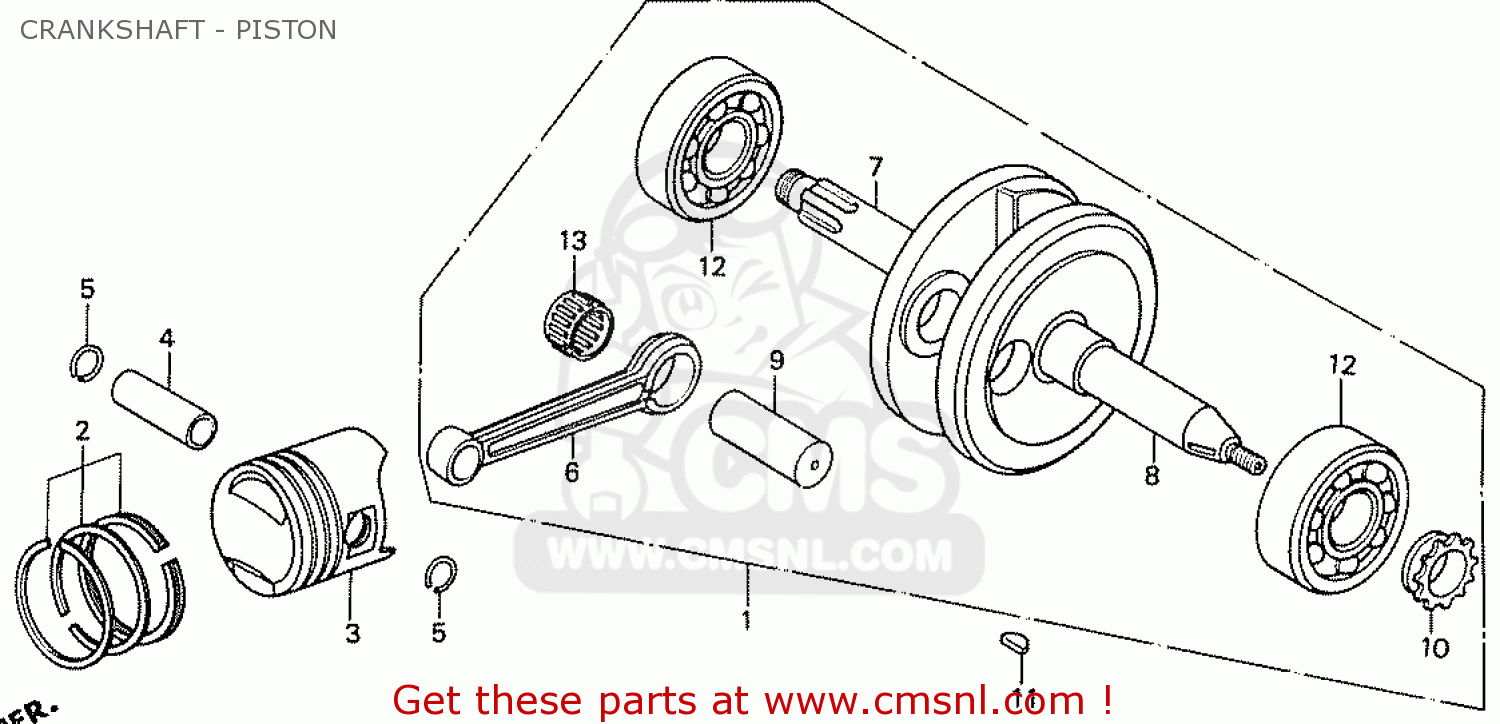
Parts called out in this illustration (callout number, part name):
1	CRANK SHAFT COMP
2	RING SET,PISTON
3	PISTON
5	CLIP, PISTON PIN
6	ROD,CONNECTING
7	CRANKSHAFT,RIGHT
8	CRANKSHAFT,LEFT
9	PIN,CRANK
10	SPROCKET, TIMING
11	KEY,WOODRUFF,4MM.
12	B/BRG RAD N/COM
13	B/BRG RAD N/COM
